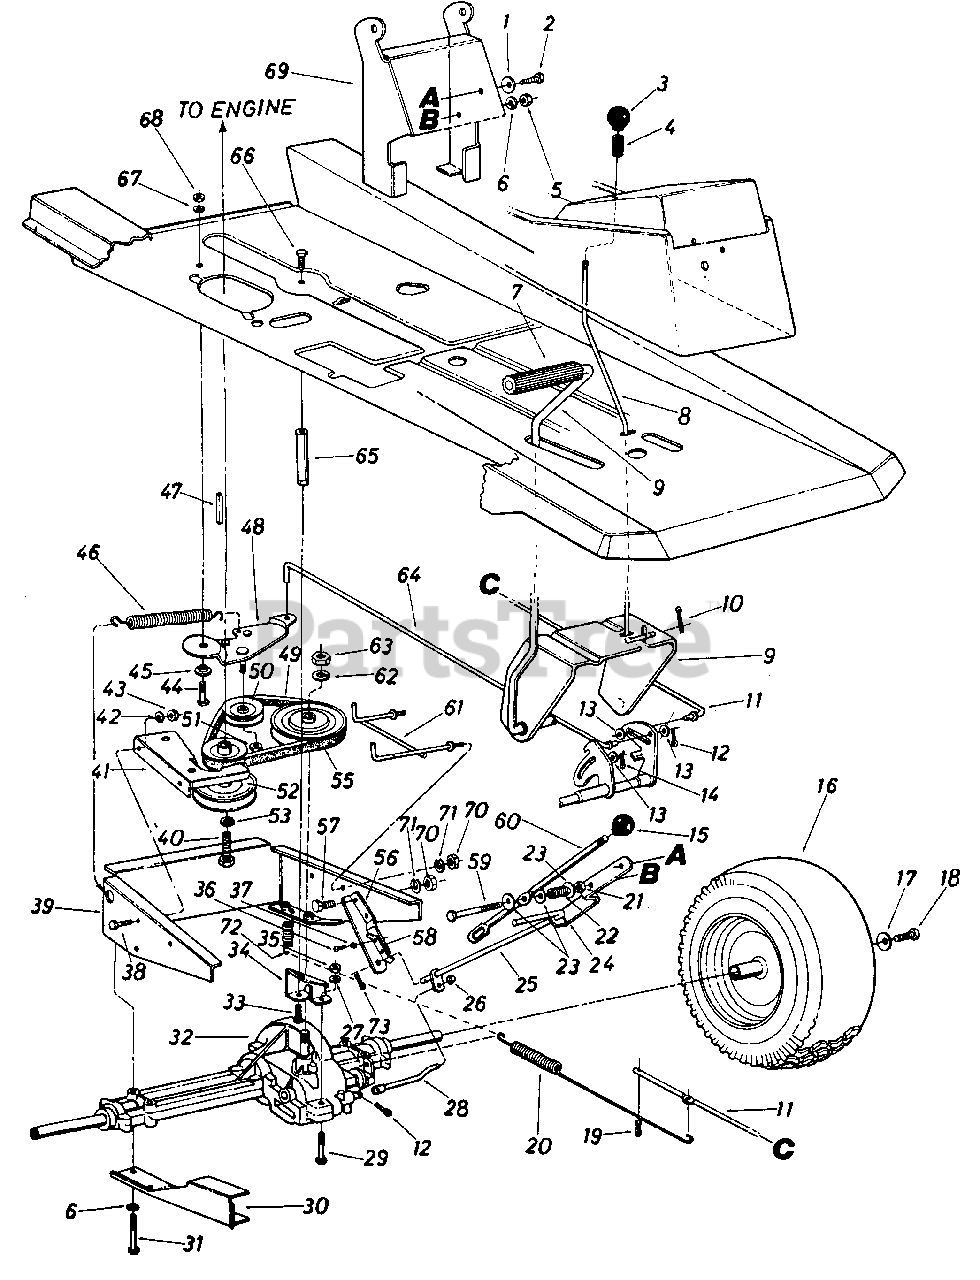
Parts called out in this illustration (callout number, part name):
1	WASHER-BELL .337 X .867 X .057
2	SCREW-HEX WASH HD
4	SPRING-COMPRESSION
5	NUT-HEX 5/16-18
6	WASHER-LOCK-5/16
7	PAD-FOOT
8	ROD-BRAKE LOCK
9	PEDAL ASSY-BRAKE
10	PIN-COTTER-3/32 DIA X .75
11	ROD-BRAKE
12	PIN-COTTER-1/8 DIA X 1.00
13	WASHER-FL (#46041)
14	PIN-INTERN COT-5/16 DIA
15	KNOB-BALL 1-3/8 " DIA.
17	WASHER-BELL .337 X .867 X .057
18	SCREW-CAP LOCK 5/16-24 X .75
19	PIN-COTTER-1/8 DIA X 1.25
20	SPRING-EXTENSION
21	NUT-HEX 5/16-18
22	SPRING
23	WASHER-BELL .337 X .867 X .057
24	BRACKET-SHIFT LEVER
25	LEVER ASSY-SHIFT
27	LOCK WASHER 1/4 DIA
28	ROD-SHIFT
29	SCREW-HEX 1/4-20 X 1.75
30	GUARD-BELT-LOWER
31	SCREW-HEX 5/16-18 X 2.75
32	TRANSAXLE-1 SP
33	SCREW-HEX 3/8-24 X .75
34	BRACKET-TORQUE ROD
35	NUT-HEX 1/4-20
36	SCREW-C SINK #8X.50
38	SCREW-HEX 1/4-20 X .75
41	GUARD-ENG BELT-UPR
42	LOCK WASHER 1/4 DIA
43	NUT-HEX 1/4-20
44	SCREW-HEX 5/16-18 X .75
45	SPACER-SHLD
46	SPRING-EXTENSION
47	KEY-SQ 1/4 X 2.00
48	BRACKET ASSY-IDLER
49	BELT-V 5/8 X 30
50	PULLEY-V-BELT IDLER
51	NUT-HEX INS L-3/8-24
53	WASHER-LOCK-7/16
55	PULLEY
56	SUPPORT-SHIFT LEVER
57	SCREW-HEX 1/4-20 C .62
58	SPRING-SWITCH
59	SCREW-HEX 5/16-18 X 2.25
60	KIT-SHIFT LEVER
61	GUARD-BELT
62	WASHER-LOCK-1/2
63	NUT-HEX 1/2-13
64	ROD-CLUTCH
65	ROD-TORQUE
66	SCREW-HEX 3/8-24 X .75
67	WASHER-LOCK-5/16
68	NUT-HEX 5/16-18
69	BRACKET-SEAT
70	NUT-HEX 1/4-20
71	LOCK WASHER 1/4 DIA
72	SPRING-EXTENSION
73	PIN-COTTER-3/32 DIA X 1.00
